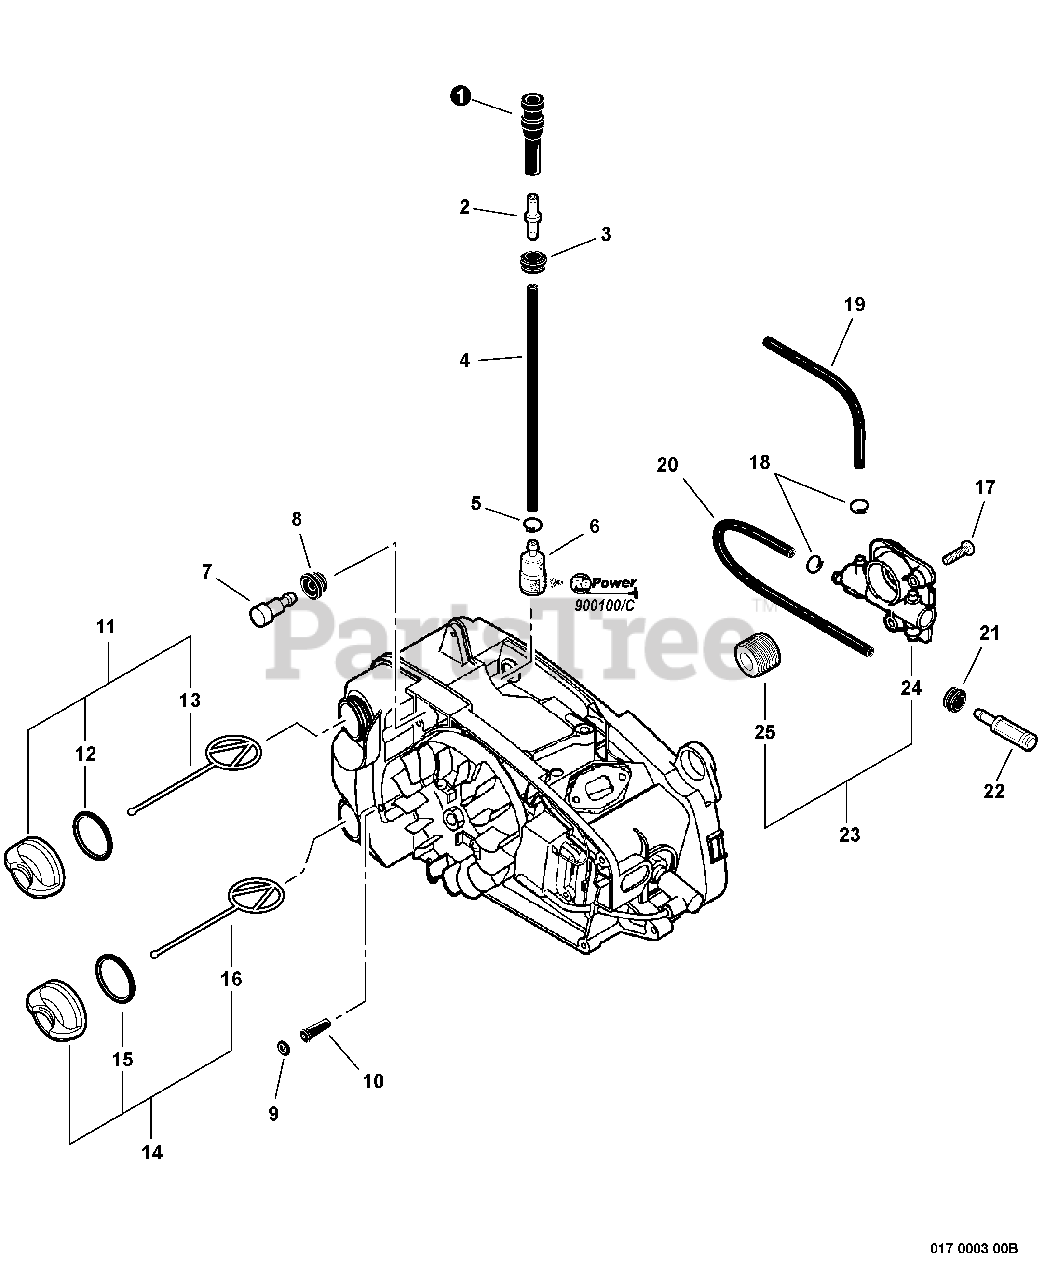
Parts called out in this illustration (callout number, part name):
1	PIPE, FUEL
2	CONNECTOR, PIPE
3	GROMMET, FUEL
4	PIPE, FUEL
5	CLIP 6 MM
6	FILTER, FUEL
7	VENT ASSY
8	GROMMET, FUEL
9	O-RING S-4
10	VENT ASSY
11	CAP ASSY
12	O-RING 18
13	CONNECTOR, CAP L= 60 MM
14	CAP ASSY - BLACK
15	O-RING 18
16	CONNECTOR, CAP L= 60 MM
17	SCREW 4×12
18	CLIP Ø6.5 MM
19	PIPE 3×6×90 MM
20	PIPE 3×6×185 MM BLACK
21	GROMMET
22	FILTER, OIL
23	AUTO-OILER KIT
24	AUTO-OILER ASSY
25	GEAR, WORM
26	REPOWER TUNE-UP KIT
